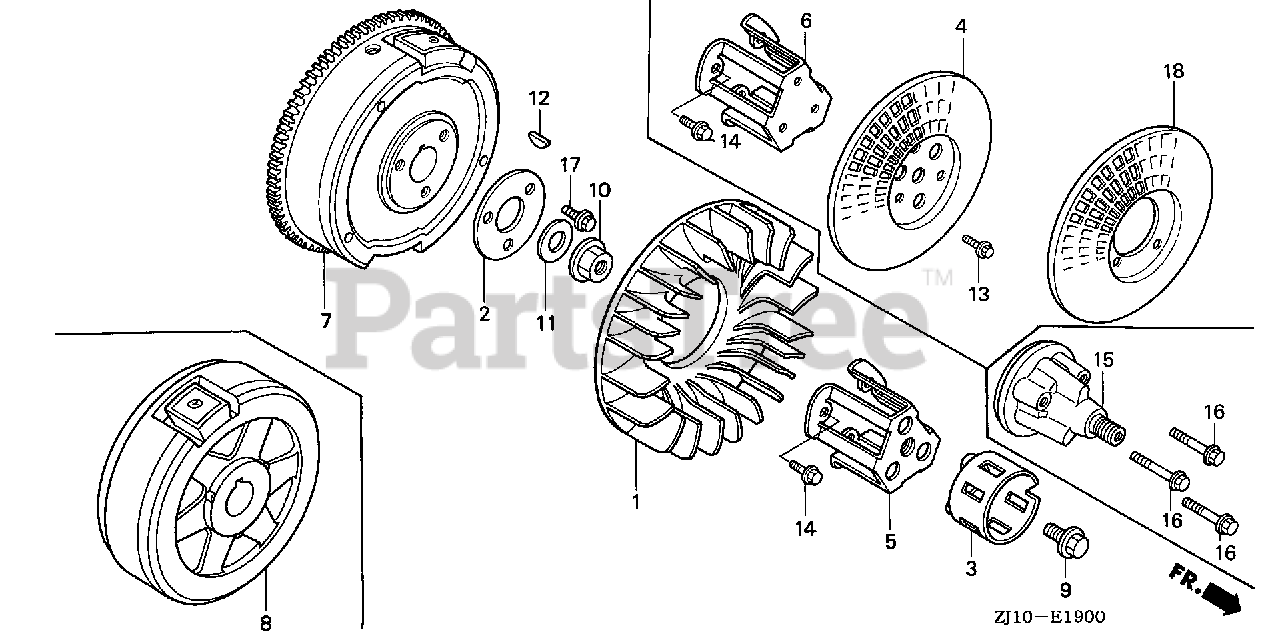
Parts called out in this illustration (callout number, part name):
1	FAN, COOLING
2	PLATE, COOLING FAN SETTING
4	GRID, SCREEN (P.T.O.)
6	HOLDER, SCREEN GRID
10	NUT, FLANGE (20MM)
11	WASHER (20MM)
12	KEY, SPECIAL WOODRUFF (25X18)
17	BOLT, FLANGE (8X16)
18	GRID, SCREEN (P.T.O.)
